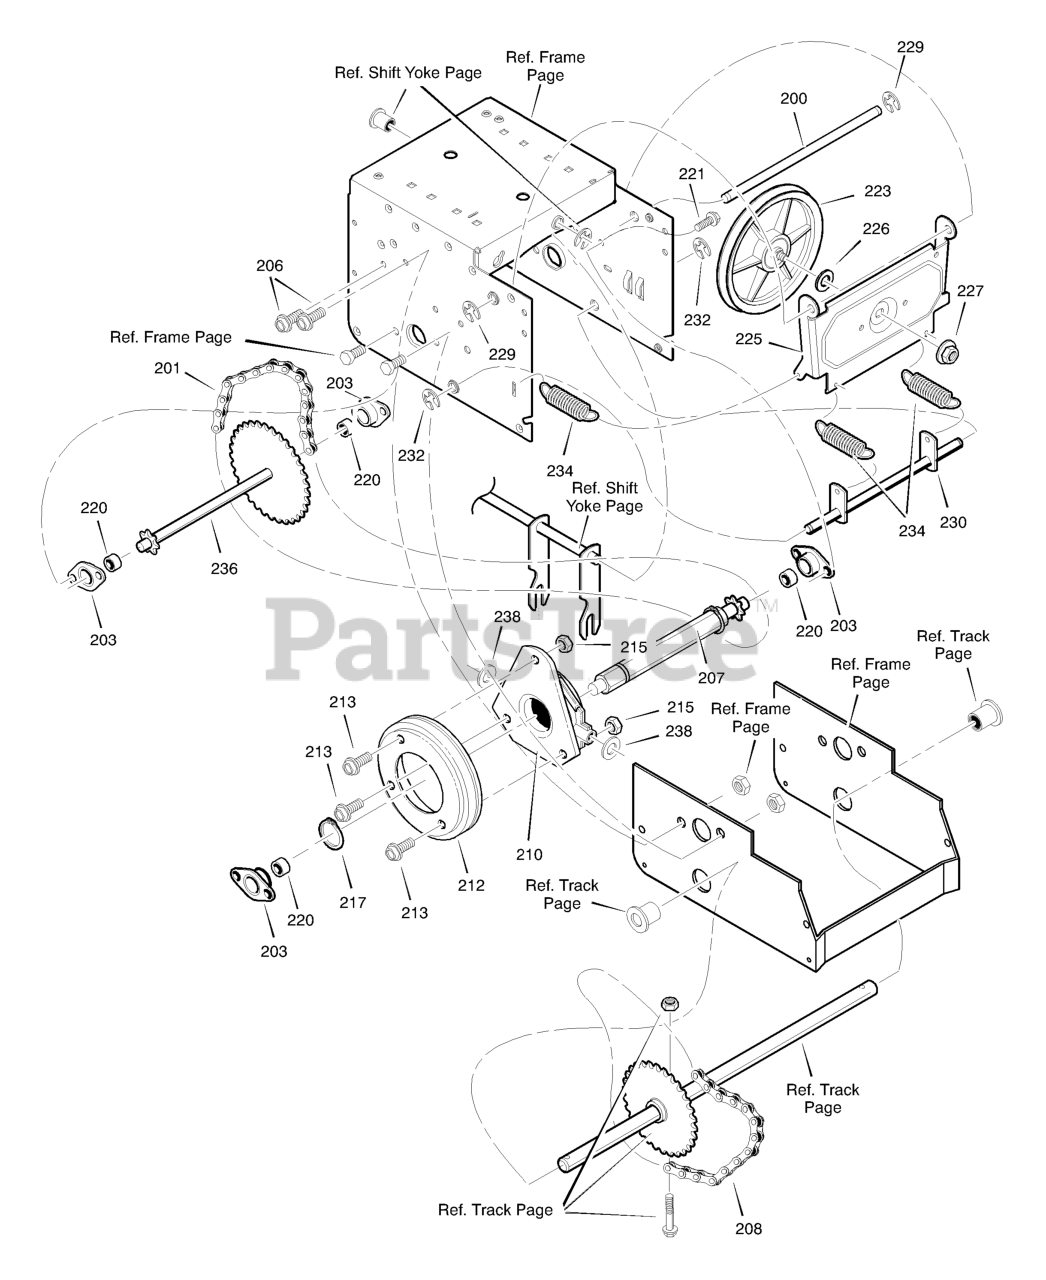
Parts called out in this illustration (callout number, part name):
200	LF AXLE, SWING PLATE YZ
201	CHAIN, ROLLER #420x19.00 LG
203	RETAINER, BEARING
206	SCREW, TAP 5/16-18 x 0.5
207	ASSY, HEX SHAFT
208	CHAIN, ROLLER #420x23.00LG
210	BEARING, TRUNION CLUTCH R
212	FRICTION WHEEL
213	SCREW, 1/4-20 x 0.63
215	NUT, KEPS HEX 1/4-20
217	RING, RETEXT
220	BEARING, BALL
221	SCREW, TAP 5/16-18 x .5
223	ASSY, FRICTION PULLEY
225	LF PLATE, SWINGING YZ
226	SPACER, FRICTION PULLEY
227	NUT, FLANGE LOCK 3/8-24
229	RETAINER, RING
230	LF ASSY, SPRING LINK YZ
232	RETAINER, RING
234	SPRING, EXTENSION
236	WLDT, INTERMED SPROCKET
238	WASHER, FLAT
